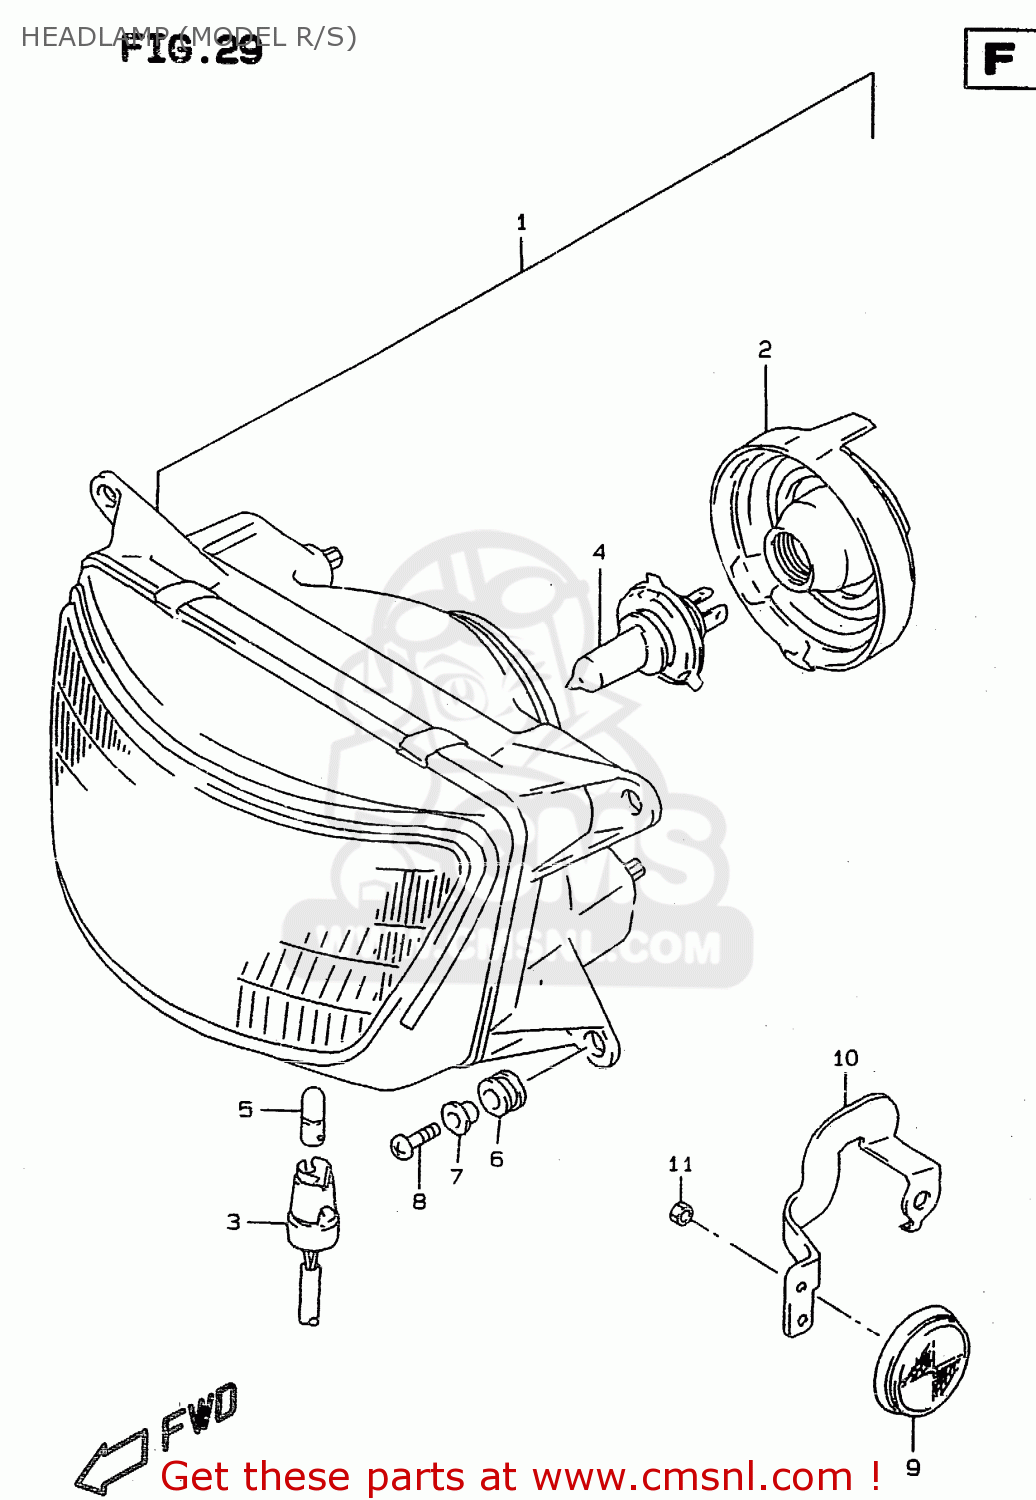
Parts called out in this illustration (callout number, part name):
1	HEADLAMP ASSY
2	COVER,SOCKET
3	CORD ASSY
4	BULB(12V60/55W,H4)
5	BULB(12V4W)
6	CUSHION
7	WASHER
8	SCREW
9	REFLECTOR,REFLEX FR
10	BRACKET,FR SIDE REFLECTOR,R
11	NUT
